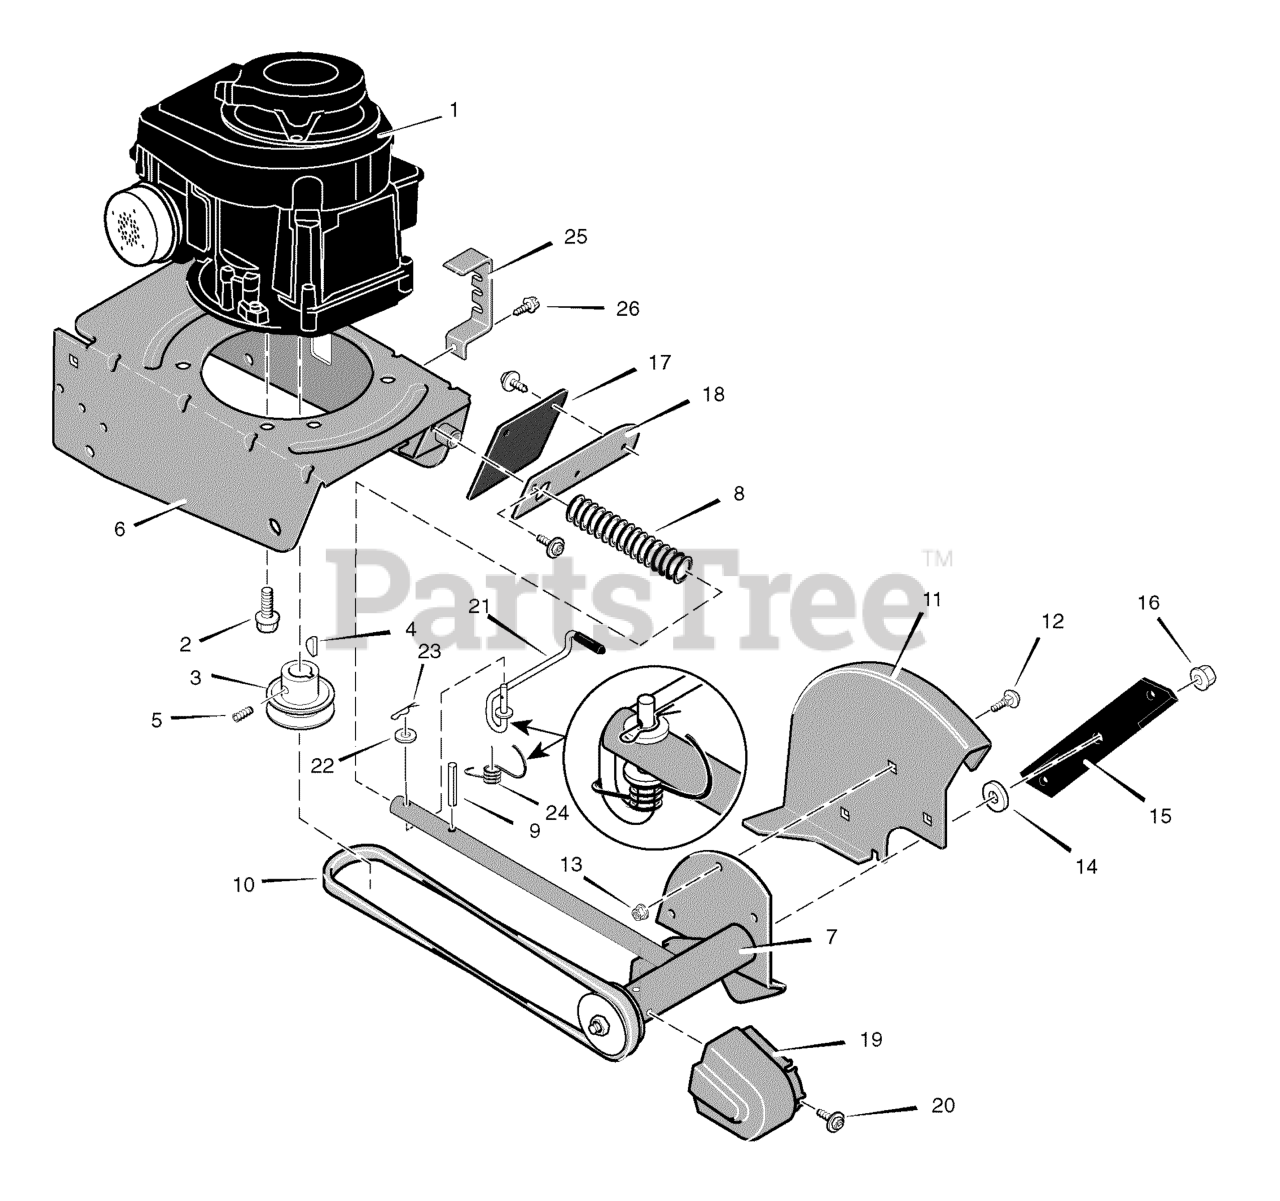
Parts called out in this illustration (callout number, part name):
2	Screw
3	Pulley, V3L
4	Key, Hi Pro #505
5	Screw, Set
6	Frame, Edger
7	Quill Assembly
8	Spring
9	Spring Pin
10	Belt, V4L
11	Blade Guard
12	Bolt, Carriage
13	NUT, 5/16-18
14	Flat washer
15	Blade, Edger
16	NUT, 1/2-20
17	Deflector, Rubber
18	Plate, Rubber Flap
19	Belt Guard
20	Screw, 10-16x.50
21	Lever, Blade
22	Washer
23	Pin, Hair
24	Spring, Torsion
25	Bracket, Index
26	Screw, 1/4-20x0.50
